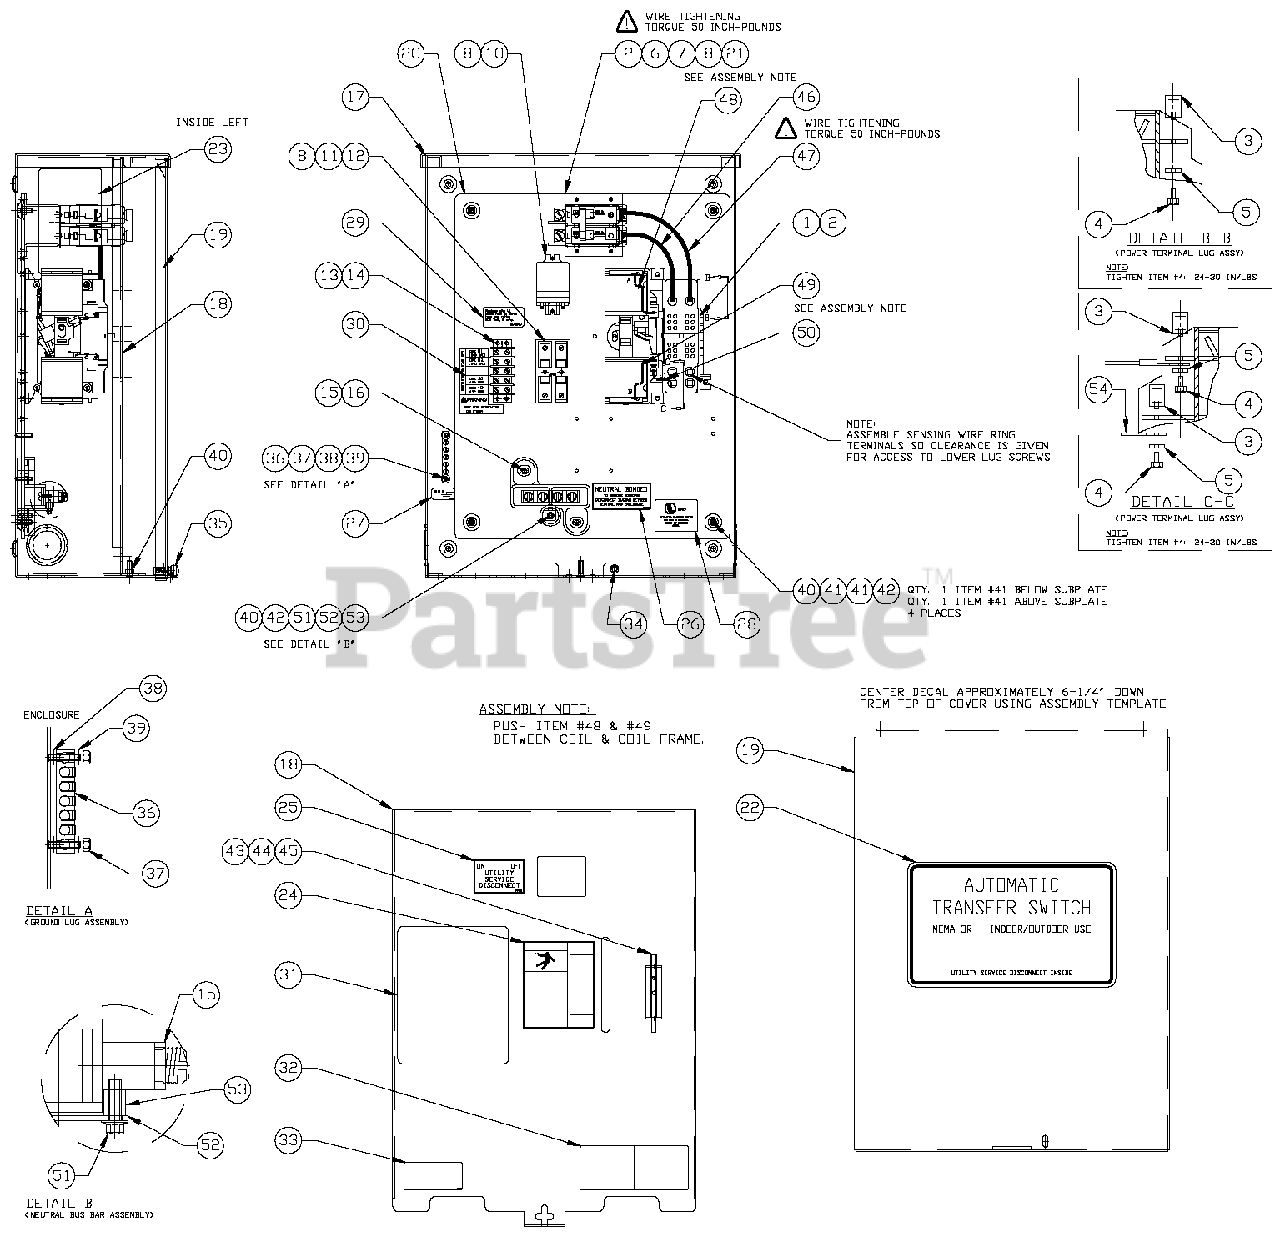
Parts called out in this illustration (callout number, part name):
1	TR SW-HSB 100A 2P 250V
2	SCREW HHTT M5-0.8 X 10 BP
3	LUG SLDLSS 1/0-#14X9/16 AL/CU
4	SCREW PPHM #10-32 X 5/16
5	WASHER, LOCK # 10
6	CB 100A 2P BACK MNT SIEMENS
7	C/BKR MOUNTING BRACKET
8	SCREW HHTT M4-0.7 X 10 BP
10	RELAY PNL 12VDC DPDT
11	FUSEBLOCK 30A 600V 2 POLE
12	FUSE 5A X BUSS HLDR73591
13	BLOCK, TERM 20A 5 X 6
14	RIVET, POP .156 X .67
15	ASSY-NEUT BLK 100A W/TAP
16	SCREW HHTT M6-1.0 X 12 MM
17	ENCLOSURE, 100/200A TRANSFER SWITCH
18	COVER, INSIDE TRANSFER SWITCH ENCL
19	COVER, TRANSFER SWITCH
20	SUBPLATE, 100/200A XFER SW
21	RISER, 100A SERVICE ENTRANCE
22	DECAL, FRNT CVR ATS 3R SER DIS
23	DECAL, XFER SW SE 100A 120/240
24	DECAL, MANUAL OPERATING HANDLE
25	DECAL, UTILITY DISCONNECT
26	DECAL, NEUTRAL CONNECTION
27	DECAL, GROUNDING LUG
28	DECAL, UL LIST HSB
29	DECAL, FUSE REPLACEMENT
30	DECAL, TERMINAL STRIP
31	DECAL, TEST SEQUENCE
32	DECAL, TERMINAL SHOCK HZD BI
33	DECAL, LIVE CIRCUIT ENG/FRN/SPN
34	NUT TRIC 1/4-20 X .525
35	THUMB SCREW 1/4-20x1/2
36	GROUND BAR (5) 4-14 AWG CONN
37	NUT HEX LOCK M4-0.7 SS NYL INS
38	WASHER SHAKEPROOF EXT #8 STEEL
39	WASHER FLAT M4
40	NUT HEX 1/4-20 SS
41	WASHER FLAT 1/4-M6 ZINC
42	WASHER LOCK M6-1/4
43	BRACKET, ARM EXTENDER
44	RIVET POP .156 X .362 AL
45	ARM EXTENDER PIN
46	WIRE ASM, 2AWG 100A 2-P T/S N1A
47	WIRE ASM, 2AWG 100A 2-P T/S N2A
50	WIRE-E1
51	SCREW HHTT M4-0.7 X 16 BP
52	BUSBAR, NEUTRAL BLOCK
53	5/16" BRASS SPACER
54	LUG DIS QK NI-S 10X45 DEG BR/T
